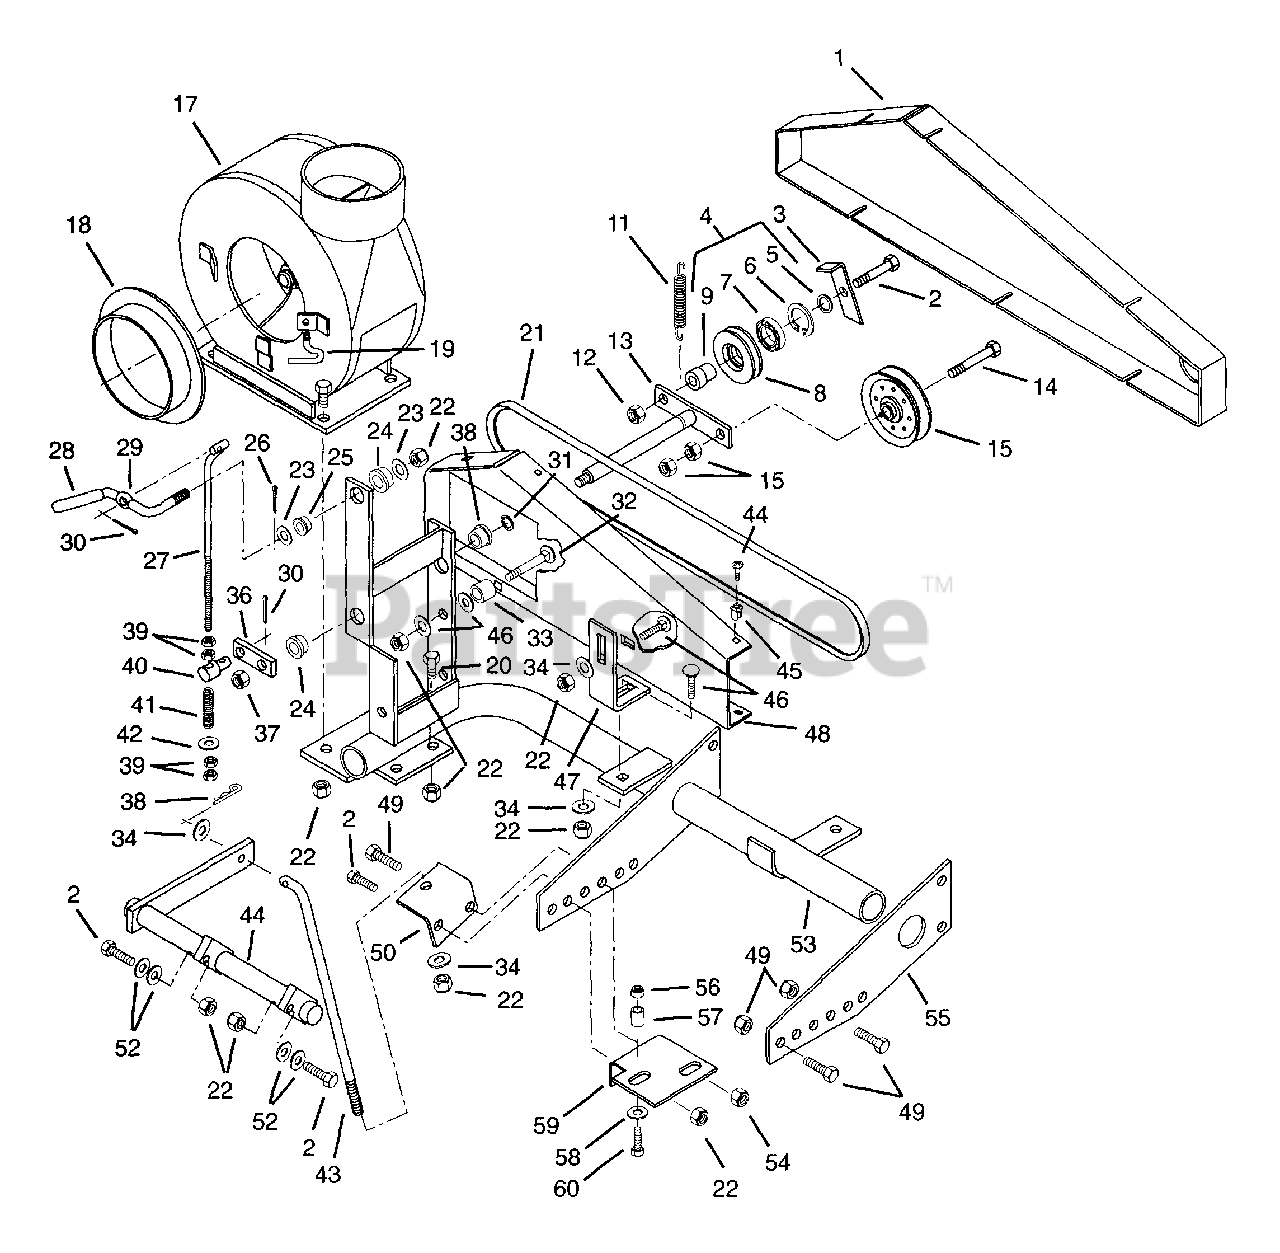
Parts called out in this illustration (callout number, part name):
1	Cover, Belt
2	Bolt-Hex .50-13 x 2.00 Grade 5
3	Guide, Belt
4	Assembly, Idler Sheave
5	Ring, Retaining
6	Ring-Retaining-Internal 2.054 x .062
7	Bearing-Ball 1.85 x .787 x .55
8	Sheave, Idler
9	Bushing, .515 x 1.00 x 1.21
10	Clip, Spring
11	Spring-Tension .063 x .62 x 2.50
12	Nut-Hex-Locking .50-13
13	Weldment, Clutch Shaft
14	Bolt-Hex .38-16 x 2.25 Grade 5
15	Sheave, Idler 4.00 x .38
16	Nut-Locking-Center .375-16
17	G-Blower Assembly
18	Adapter, Hose
19	Clamp Screw
20	Bolt-Hex .50-13 x 1.25 Grade 5
21	Belt
22	Nut-Locking-Nylon .50-13
23	Washer-Flat-Steel .531 x 1.250 x .10
24	Bushing-Flange .762 x 1.00 x .580 x 1.48
25	Bushing-Flange .515 x .750 x .745 x 1.00
26	Pin-Roll .187 x 1.00
27	Rod, Control Actuating
28	Grip
29	Lever, Control
30	Pin-Cotter .09 x .75
31	Ring-Retaining-External .689 x ,078
32	Bolt, Round Head Square Neck .50-13 x 3.00
33	Bushing .750 x 1.00 x 1.10
34	Washer-Flat-Steel .56 x 1.38 x .109
35	Weldment, Control Support
36	Arm, Control
37	Nut-Locking-Nylon .38-24 with Insert
38	Pin-Cotter .05 x 1.157
39	Nut-Hex .31-18
40	Pivot
41	Spring-Compression .063 x .480 x 1.50
42	Washer-Flat-Steel .344 x .688 x .065
43	Rod, Blower Frame Support
44	Screw, Machine .25-20 x .50
45	Grommet, Plastic
46	Bolt-Round Head Square Neck .50-13 x 1.25
47	Bracket, Guard Support
48	Guide, Channel
49	Bolt-Hex .62-11 x 2.00
50	Bracket, Vacuum Support
51	Weldment, Vacuum Support
52	Washer-Flat-Steel .531 x 1.00 x .063
53	Weldment, Blower Support Frame
54	Nut-Locking-Nylon .62-11
55	Plate, Frame Mounting
56	Nut-Locking-Nylon .38-16
57	Bushing .407 x .625 x .813
58	Washer-Flat-Steel .375 x 1.125 x .065
59	Bracket, Rear Centering
60	Bolt-Hex .38-16 x 2.00
